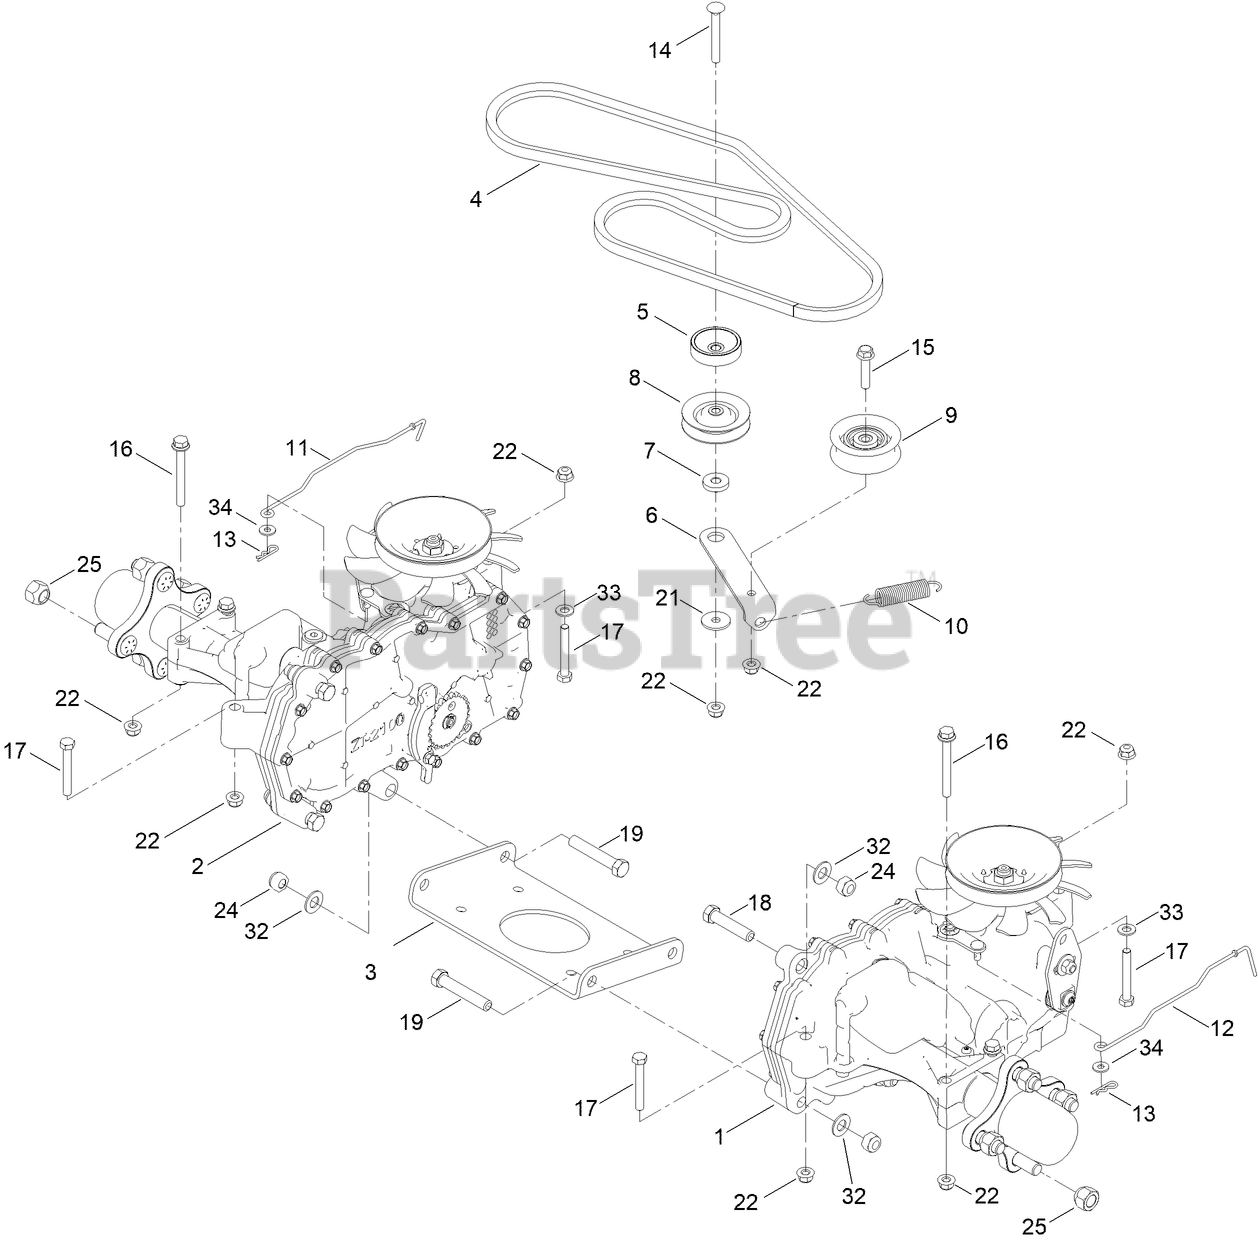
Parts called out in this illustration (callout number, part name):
1	LH HYDRO TRANSAXLE ASM
2	RH HYDRO TRANSAXLE ASM
3	CROSSPLATE-HYDRO
4	V-BELT
5	SPACER
6	ARM-IDLER
7	SPACER-IDLER ARM
9	PULLEY-IDLER, FLAT
10	SPRING-PEDAL, RETURN
11	ROD-BYPASS, RH
12	ROD-BYPASS, LH
14	SCREW-CARR
15	SCREW-HHF
16	SCREW-HHF
17	SCREW-HH
18	SCREW-HH
19	SCREW-HH
21	WASHER-PIVOT
22	NUT-HF, NI
24	NUT-LOCK, NI
25	NUT-LUG
32	WASHER-FLAT
33	WASHER-PLAIN
34	WASHER
